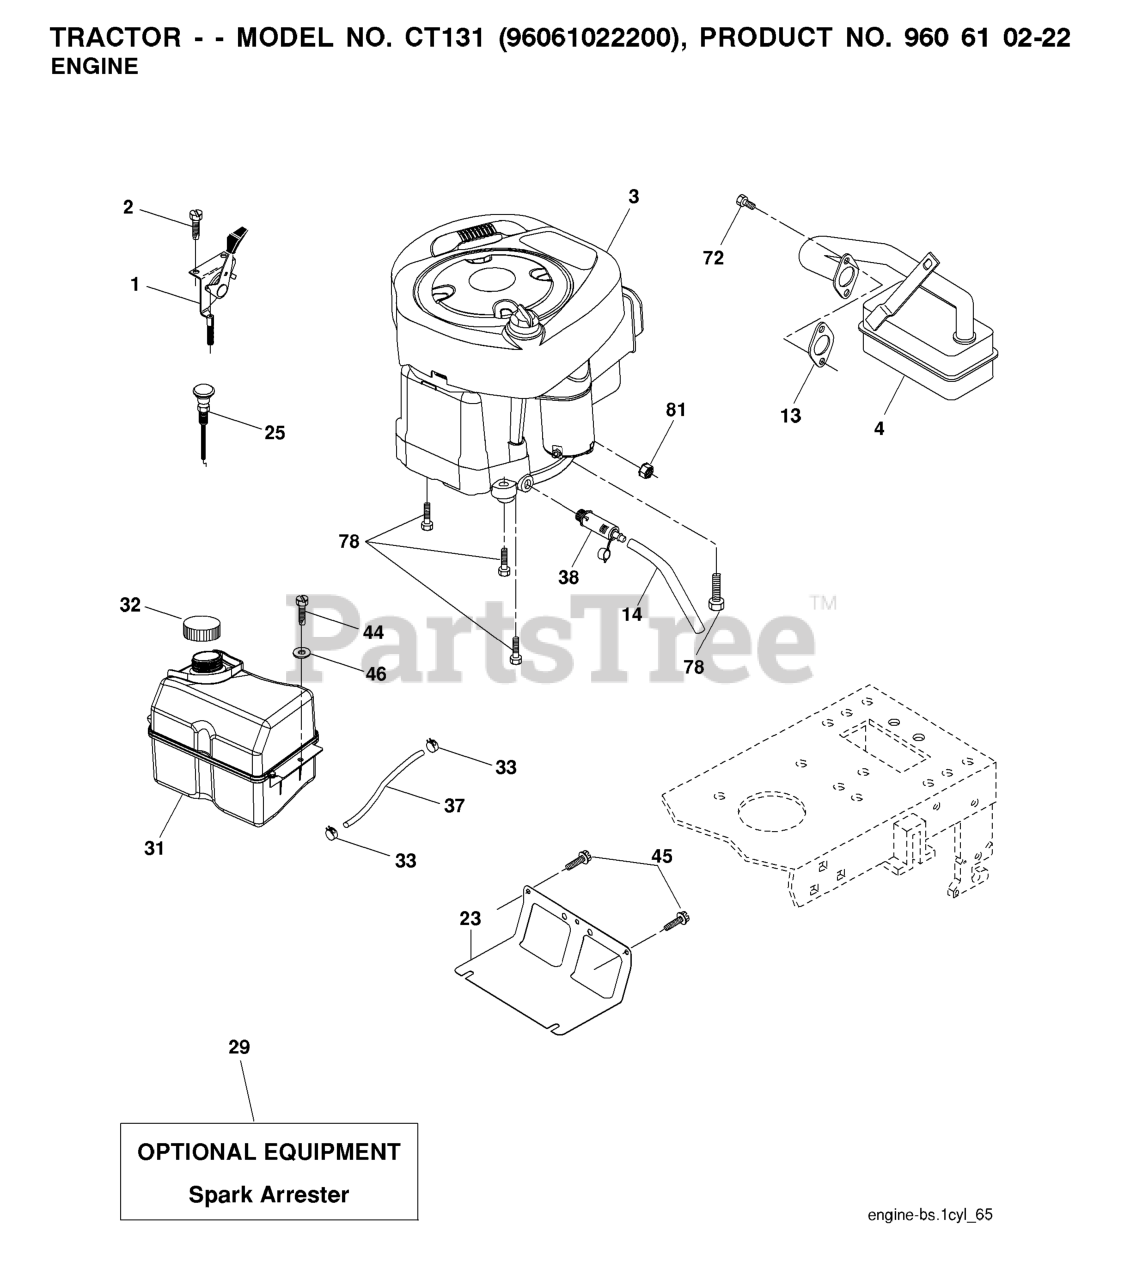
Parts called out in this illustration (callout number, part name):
1	CONTROL.THROTTLE/CHOKE.BLACK
2	SCREW
4	MUFFLER.B&S.MODEL.21.11HP.OHV
13	REPL BY 532 27 22-93
14	TUBE, DRAIN OIL ASM.
23	SHIELD.BROWNING.DBR.GUARD
25	KNOB.ERGO.EXTENDED.RED (1 2)
29	KIT.SPARK ARRESTOR 794945 B&S
31	TANK FUEL
32	FUEL CAP
33	HOSE CLAMP
37	LINE.FUEL.20
38	PLUG DRAIN OIL EASY
44	SCREW HEXWSHR 1/4-20X3/4
45	SCREW, 3/8-16X3/4
72	SCREW.SOCKET HD.5/16-1
78	SCREW.3/8-16
81	NUT
